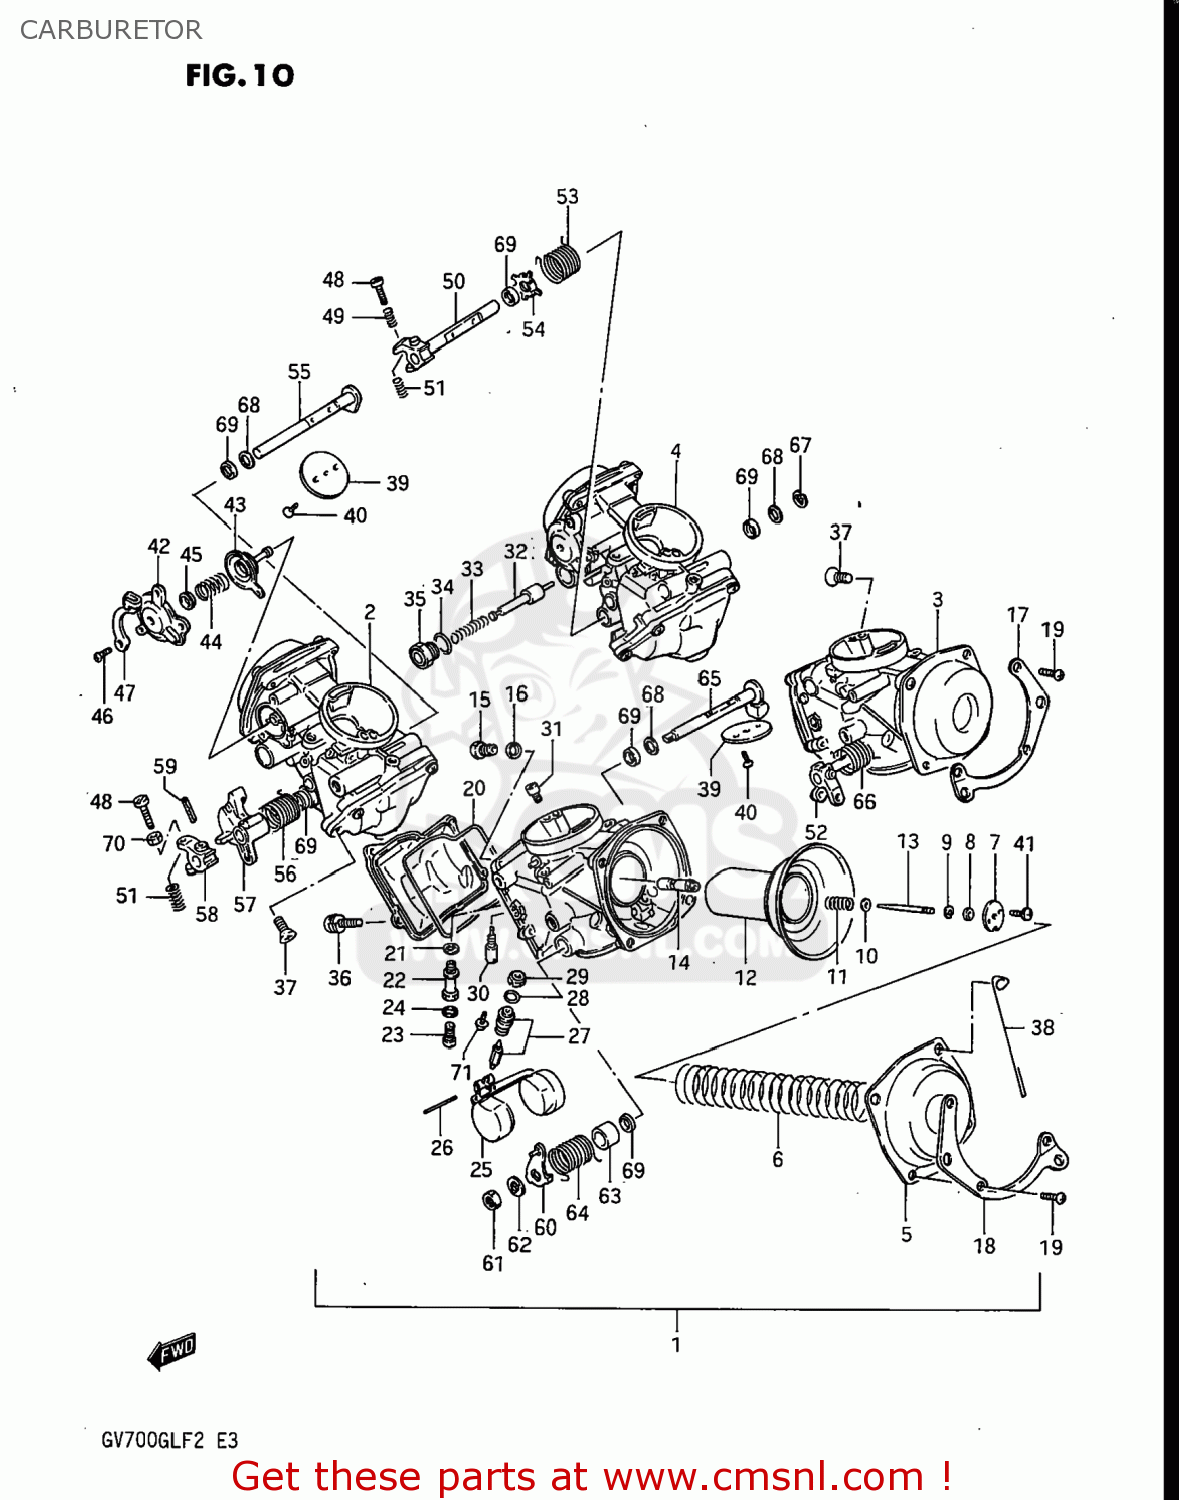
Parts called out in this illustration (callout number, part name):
1	CARBURETOR ASSEMBLY
2	CARBURETOR ASSEMBLY
3	CARBURETOR ASSEMBLY
4	CARBURETOR ASSEMBLY
5	COVER
6	SPRING,DIAPHRAGM
7	PLATE
8	RING
9	CLIP,NEEDLE
10	WASHER
11	SPRING
12	DIAPHRAGM,CARBURETOR
13	NEEDLE JET
14	JET,NEEDLE
15	SCREW
16	WASHER,NEEDLE NOZZLE
17	BRACKET
18	BRACKET
19	SCREW 5X10
20	GASKET,FLOAT CHAMBER
21	GASKET (NAS)
22	HOLDER,MAIN JET
23	JET
24	WASHER
25	FLOAT
26	PIN,FLOAT
27	VALVE ASSY,NEEDLE
28	O-RING,NEEDLE VALVE
29	FILTER
30	JET,PILOT(25)
31	JET
32	PLUNGER
33	SPRING,STARTER PLUNGER
34	O RING
35	HOLDER,GUIDE
36	SCREW
37	SCREW
38	CLIP
39	VALVE,THROTTLE
40	SCREW
41	SCREW
42	COVER
43	DIAPHRAGM ASSY
44	SPRING
45	PLATE
46	SCREW
47	BRACKET
48	SCREW
49	SPRING
50	SHAFT,THROTTLE
51	SPRING,THROTTLE SCREW
52	SHAFT,THROTTLE
53	SPRING,THROTTLE VALVE
54	PLATE
55	SHAFT,THROTTLE
56	SPRING,THROTTLE VALVE
57	LEVER,THROTTLE
58	LEVER,THROTTLE
59	PIN,THROTTLE SHAFT
60	LEVER,THROTTLE
61	NUT 8MM
62	WASHER
63	RING
64	SPRING,THROTTLE VALVE
65	SHAFT,THROTTLE
66	SPRING,THROTTLE VALVE
67	E RING
68	GASKET,THROTTLE SHAFT (NAS)
69	SEAL,THROTTLE SHAFT
70	NUT
71	SCREW
